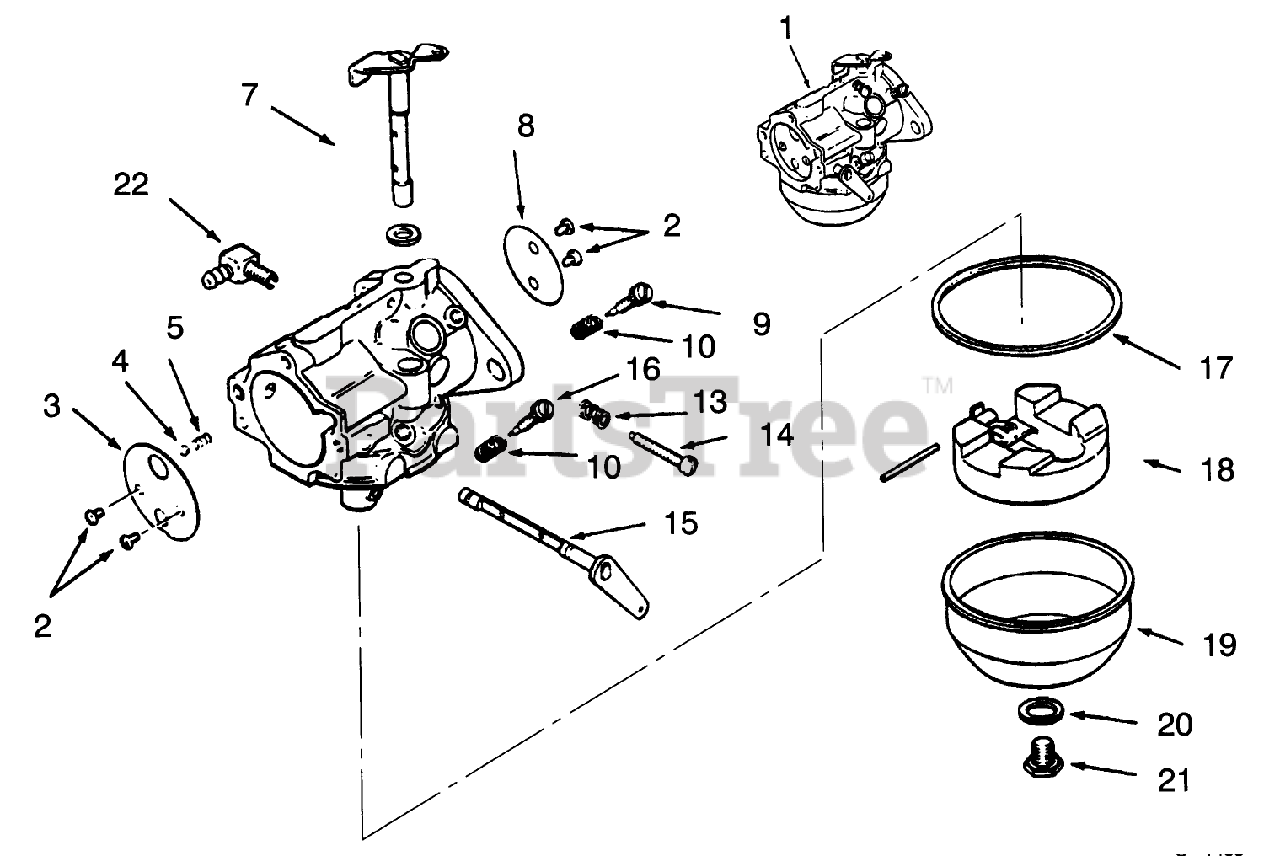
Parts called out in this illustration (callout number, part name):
1	KOHLER 47-853-20
2	KOHLER 25-086-27
3	KOHLER 47-146-08
4	KOHLER 25-194-01
5	KOHLER 25-089-03
7	KOHLER 457-144-21
8	KOHLER 25-146-02
9	KOHLER 25-368-01
10	KOHLER 25-089-02
13	KOHLER 25-089-04
14	KOHLER 25-086-26
15	KOHLER 47-090-38
16	Main-Needle
17	KOHLER 25-041-04
18	KOHLER 25-757-09
19	KOHLER 25-104-01
20	KOHLER 25-041-03
21	KOHLER 25-100-05
